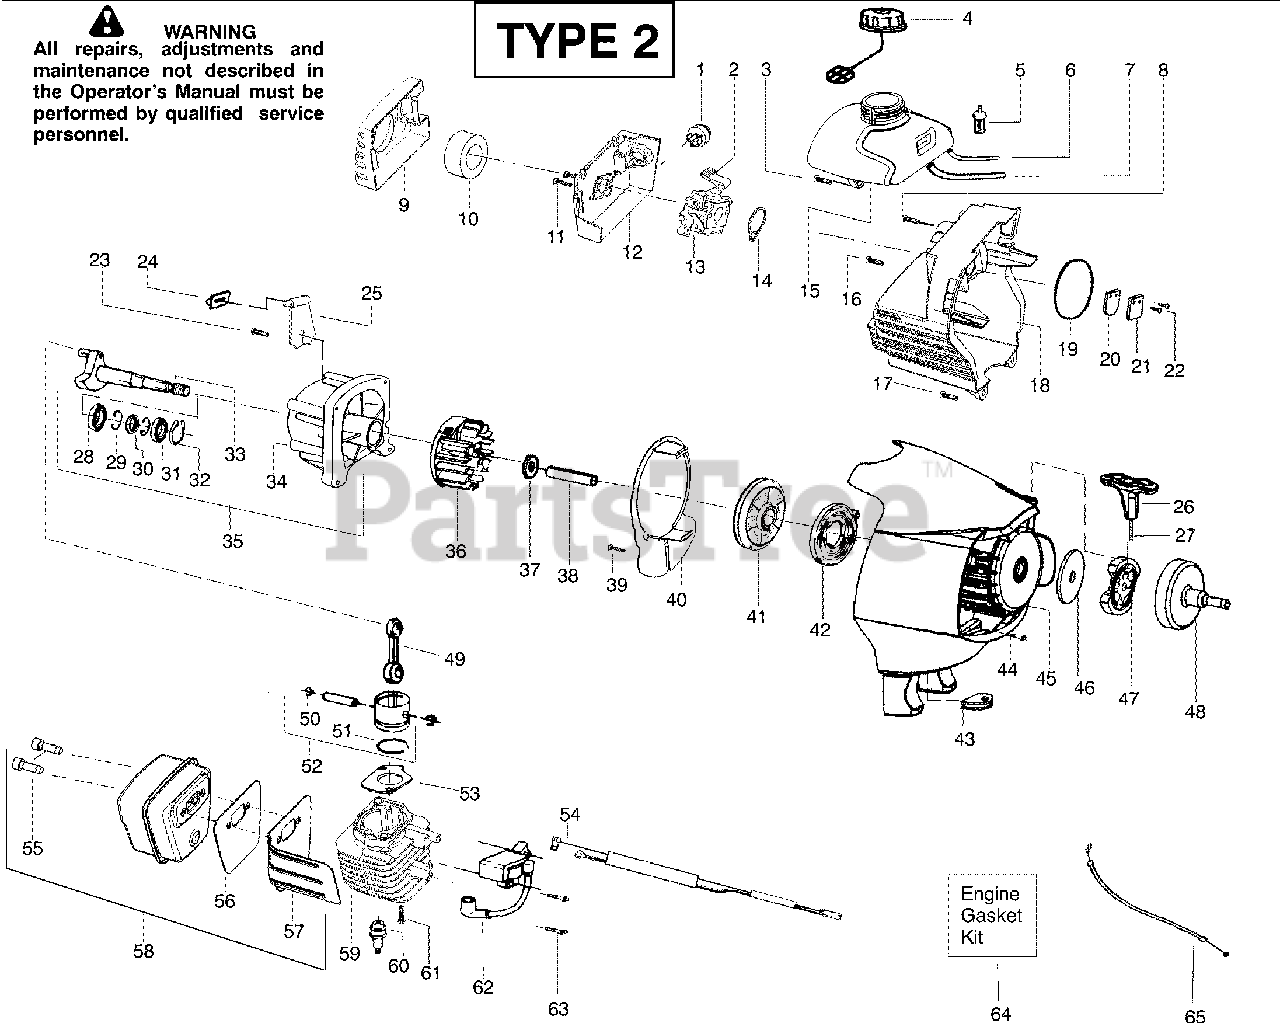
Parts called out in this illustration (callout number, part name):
1	Bulb-Purge
2	Kit-Choke Lever
3	Screw-tank
4	Cap-Fuel w/ret.
5	Assy-Fuel pickup
6	Kit-Fuel line
7	Kit-Fuel/Purge line
9	Cover-Air box
10	Filter-Air
11	Screw-Carb.
13	Kit-Carb assy. (C1U-W32)
14	Seal-Carb. (kit)
15	Assy-Fuel Tank
16	Screw-Crankcase
17	Screw-Shroud
18	Assy-Rear Shroud
19	O-ring-Shroud (kit)
20	Valve-Reed
21	Stop-Reed
22	Screw-Reed stop
23	Screw-Retainer
24	Isolator-Tank
25	Ret.-Tank
26	Handle-Starter
27	Kit-Rope
28	Bearing-Inner
29	Retainer
31	Bearing-Outer
32	Ret.-Crankshaft
33	Assy-Crankshaft
34	Assy-Crankcase
35	Assy-C’case/C’shaft
36	Assy-Flywheel
39	Screw-Baffle
40	Plate-Baffle
41	Kit-Pulley
42	Spring-Starter
44	Screw-F/hsg.
45	Assy-Fan Housing
46	Washer-Clutch
47	Assy-Clutch
48	Assy-Drum/Adapter
49	Assy-Conn. Rod
50	Ret.-Piston pin
51	Ring-Piston
52	Kit-Piston
53	Gasket-Cylinder (kit)
54	Assy-Leadwire
55	Bolt-Muffler 1/4"-20
56	Gasket-Muffler (kit)
58	Kit-Muffler
59	Cylinder
60	Plug-Spark(RCJ-6Y)
61	Bolt-Cyl. 1/4"-20
62	Module-Ignition
63	Screw-Module
64	Kit-Gasket/Seal
65	Assy-Throttle cable
